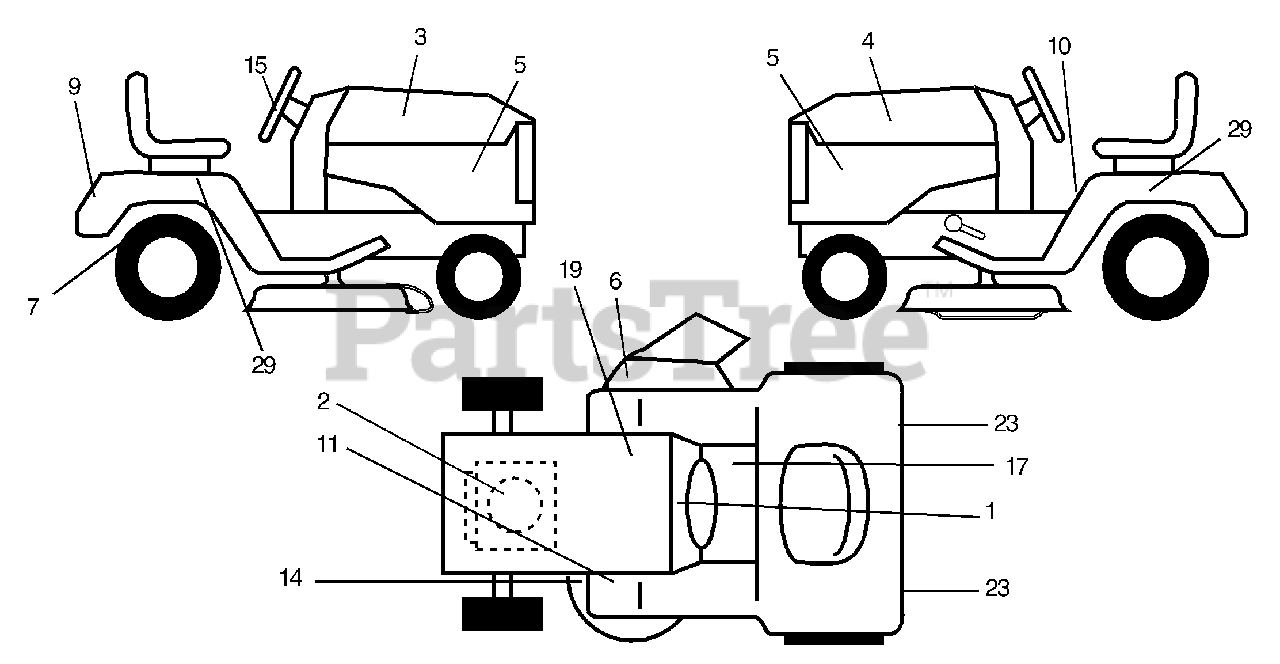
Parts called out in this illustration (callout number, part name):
1	Decal, Dash
2	Decal, Engine
3	Decal, Hood, RH
4	Decal, Hood, LH
5	Decal, Hood Side Panel
6	Decal,Warning
7	Decal, By Pass Fender
9	Decal
10	Decal,Danger
11	Decal, Clutch/Brake
14	Decal, V-Belt Schematic
15	Decal, Ins. Whl. Strg.
17	Decal, Saddle Brake Parking
19	Decal, Battery
23	Reflector, Taillight
29	Decal, Fender Auto Trans
